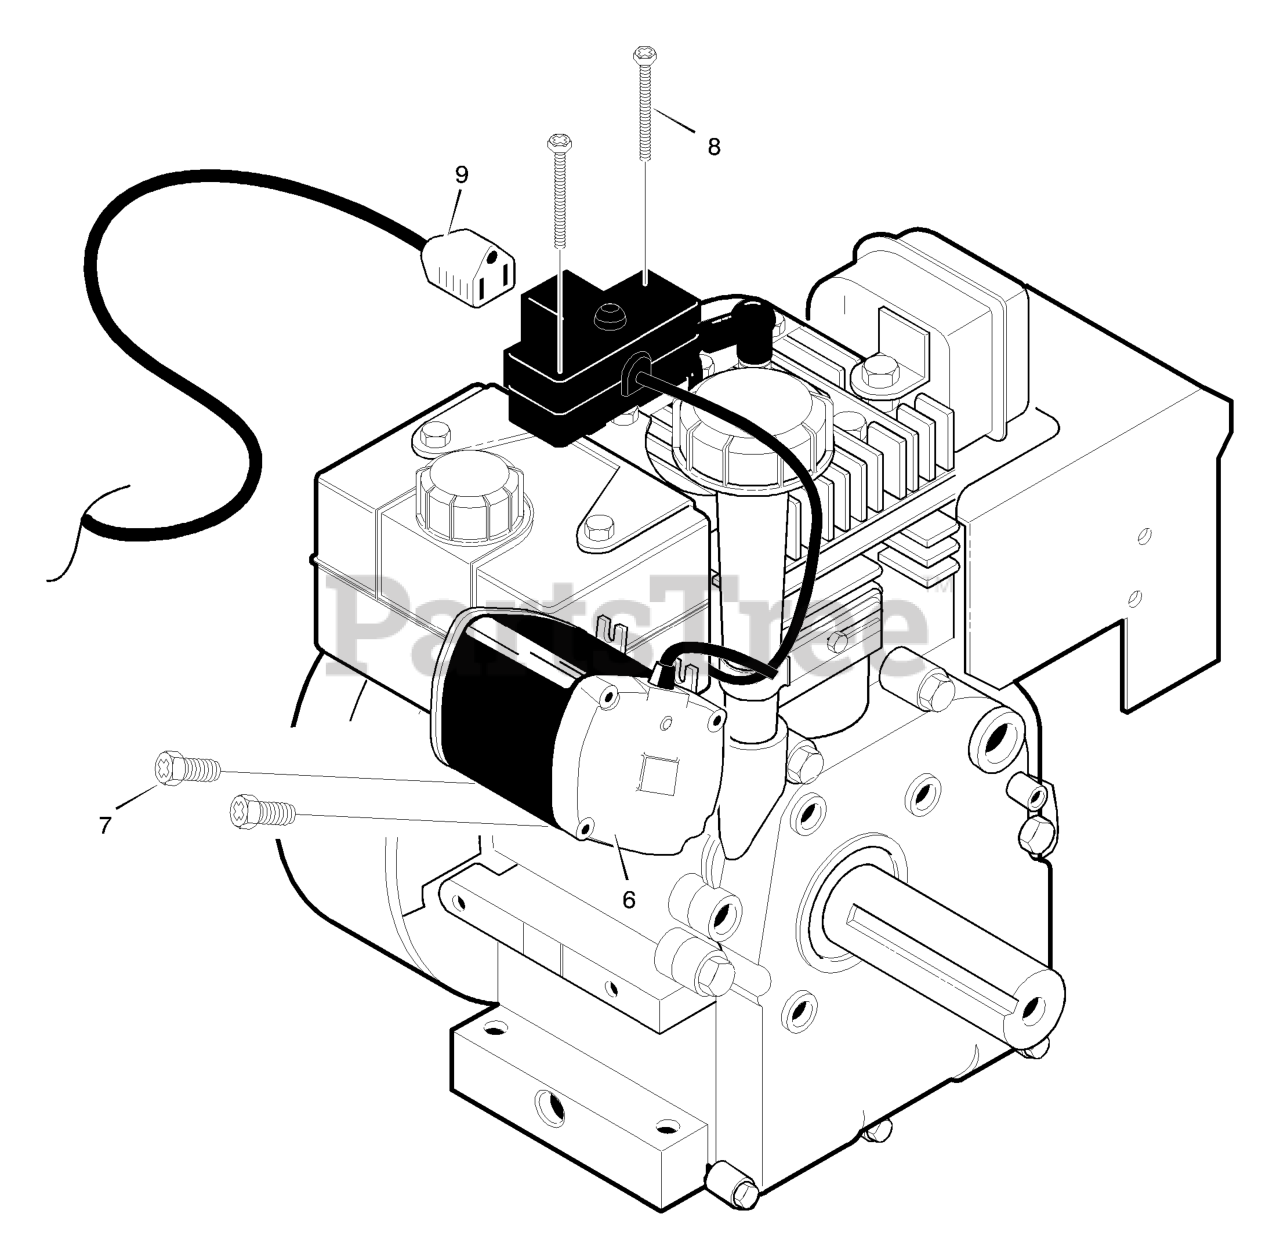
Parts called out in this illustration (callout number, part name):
6	MOTOR, STARTER (220V) TC1A173-125
8	SCREW
9	CORD, STARTER
